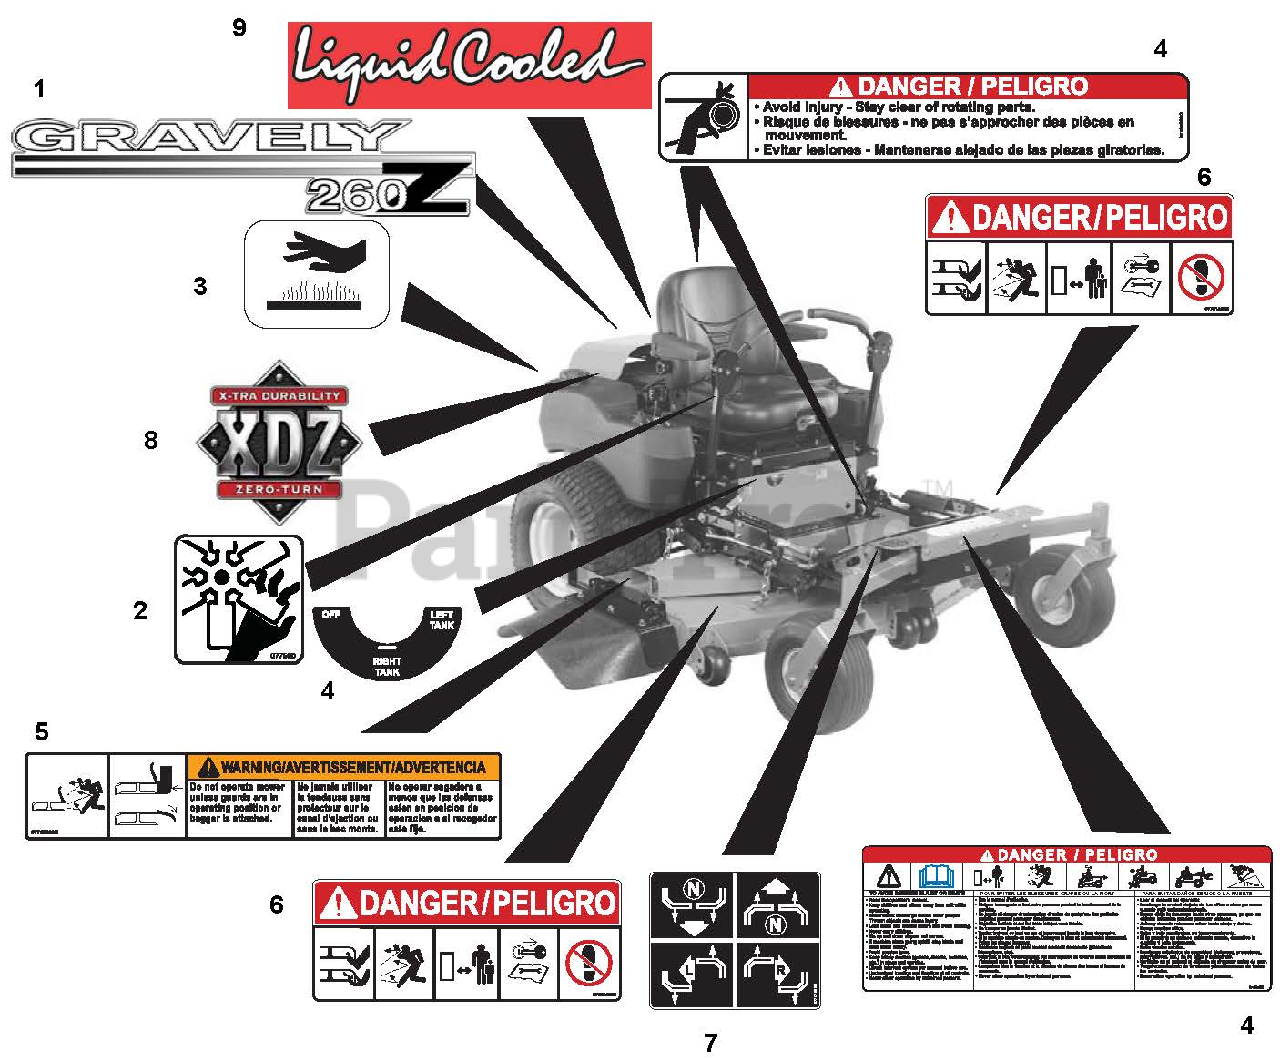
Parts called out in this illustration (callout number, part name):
1	Decal, PM-252Z Hood
1	Decal, PM-260Z Hood
1	Decal, PM-272Z Hood
1	Decal, PM-266Z Hood
2	Decal, Danger Fan
3	Decal, Hot Surface
4	Set, Decal – Common Danger/Fuel
5	Decal, Warning
6	Decal, Mower Pan Head Danger
7	Decal, Instructional
8	Decal, XDZ
9	Decal, Liquid Cooled
